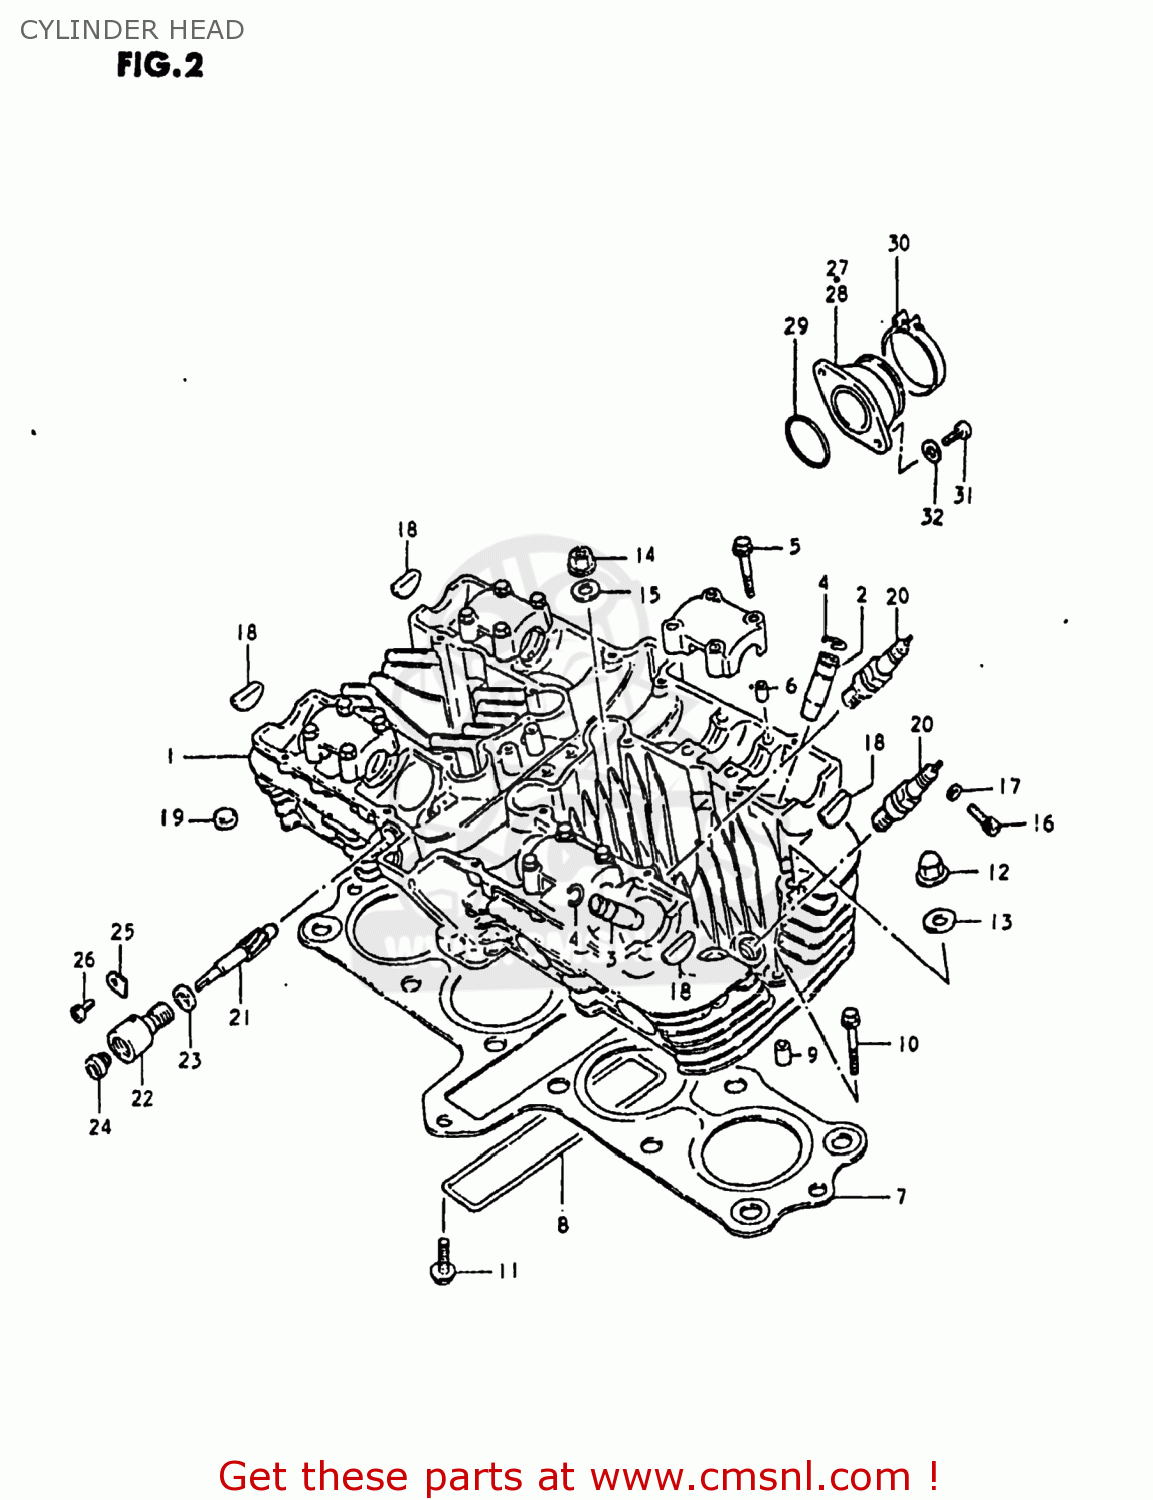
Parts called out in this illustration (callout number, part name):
1	HEAD ASSEMBLY,CYLINDER
2	GUIDE,INTAKE VALVE
3	GUIDE,EXHAUST VALVE
4	RING,SNAP
5	BOLT(6X39)
6	PIN(6.2X8X11)
7	GASKET,CYLINDER HEAD (MCA)
8	O RING(D:3,ID:26X157)
9	PIN
10	BOLT,UNDER
11	BOLT
12	NUT
13	GASKET (NAS)
14	NUT
15	WASHER(10.5X22X2.3)
16	BOLT
17	GASKET(5.3X9.3X1.2) (NAS)
18	PLUG
19	PAD
20	SPARK PLUG
21	GEAR,TACHOMETER DRIVEN
22	SLEEVE,TACHOMETER DRIVE
23	SEAL,TACHOMETER DRIVEN
24	SEAL,OIL(5X12X8)
25	PLATE,TACH DRIVE GEAR SLEEVE
26	SCREW(5X12)
27	PIPE,INTAKE,R
28	PIPE,INTAKE,L
29	O-RING (D:2.4 ID:39.7)
30	CLAMP
31	SCREW
32	WASHER
